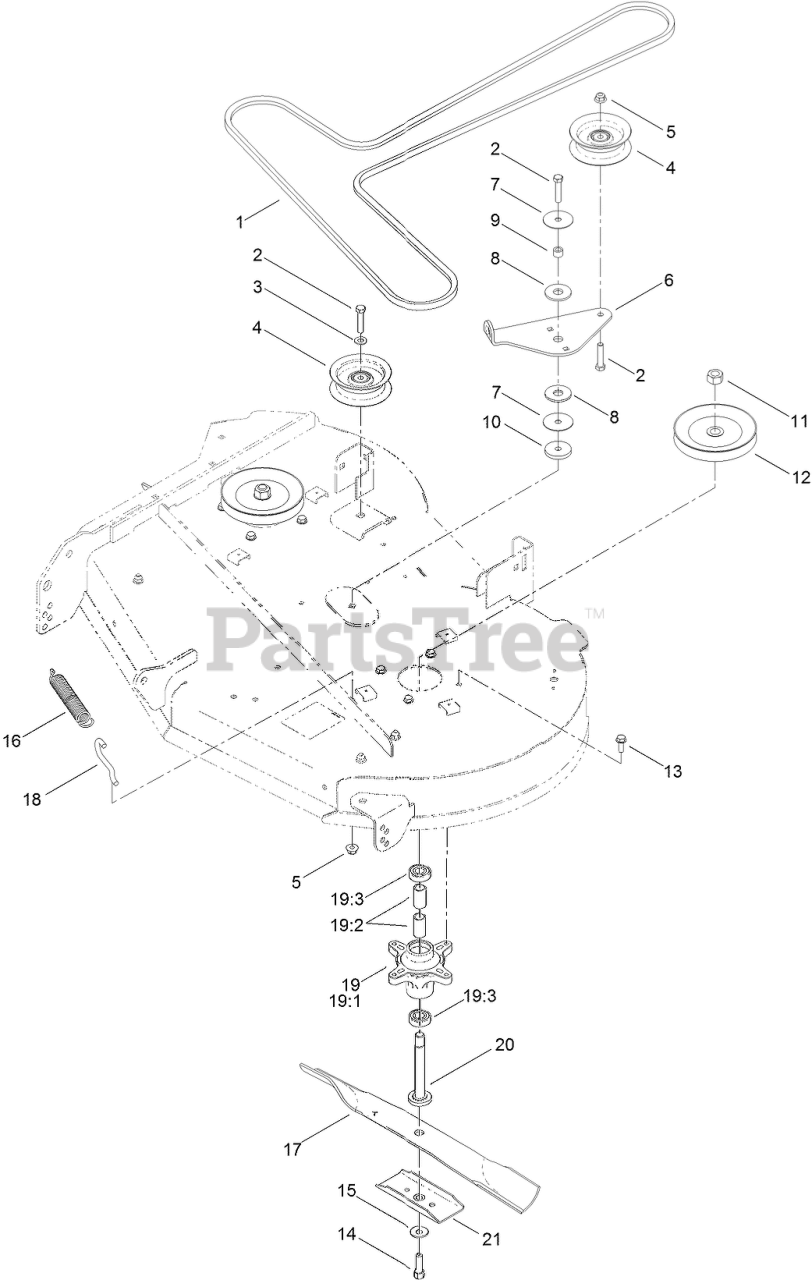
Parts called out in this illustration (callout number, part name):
1	V-BELT
2	SCREW-HH
3	WASHER-FLAT
4	PULLEY-IDLER, FLAT
5	NUT-HF, NI
6	ARM-IDLER
7	WASHER
8	WASHER-FRICTION, COMPOSITE
9	SPACER
10	WASHER-PLAIN
11	NUT-HEX
12	Pulley
13	SCREW-TAPTITE
14	SCREW-HH
15	WASHER-BELLEVILLE
16	SPRING-EXTENSION
17	BLADE-21.6 INCH
18	HOOK-RETURN, SPRING
19	SPINDLE ASM
19:1	SPINDLE
19:2	SPACER
19:3	BEARING-BALL
20	SHAFT-SPINDLE
21	STIFFENER-BLADE
